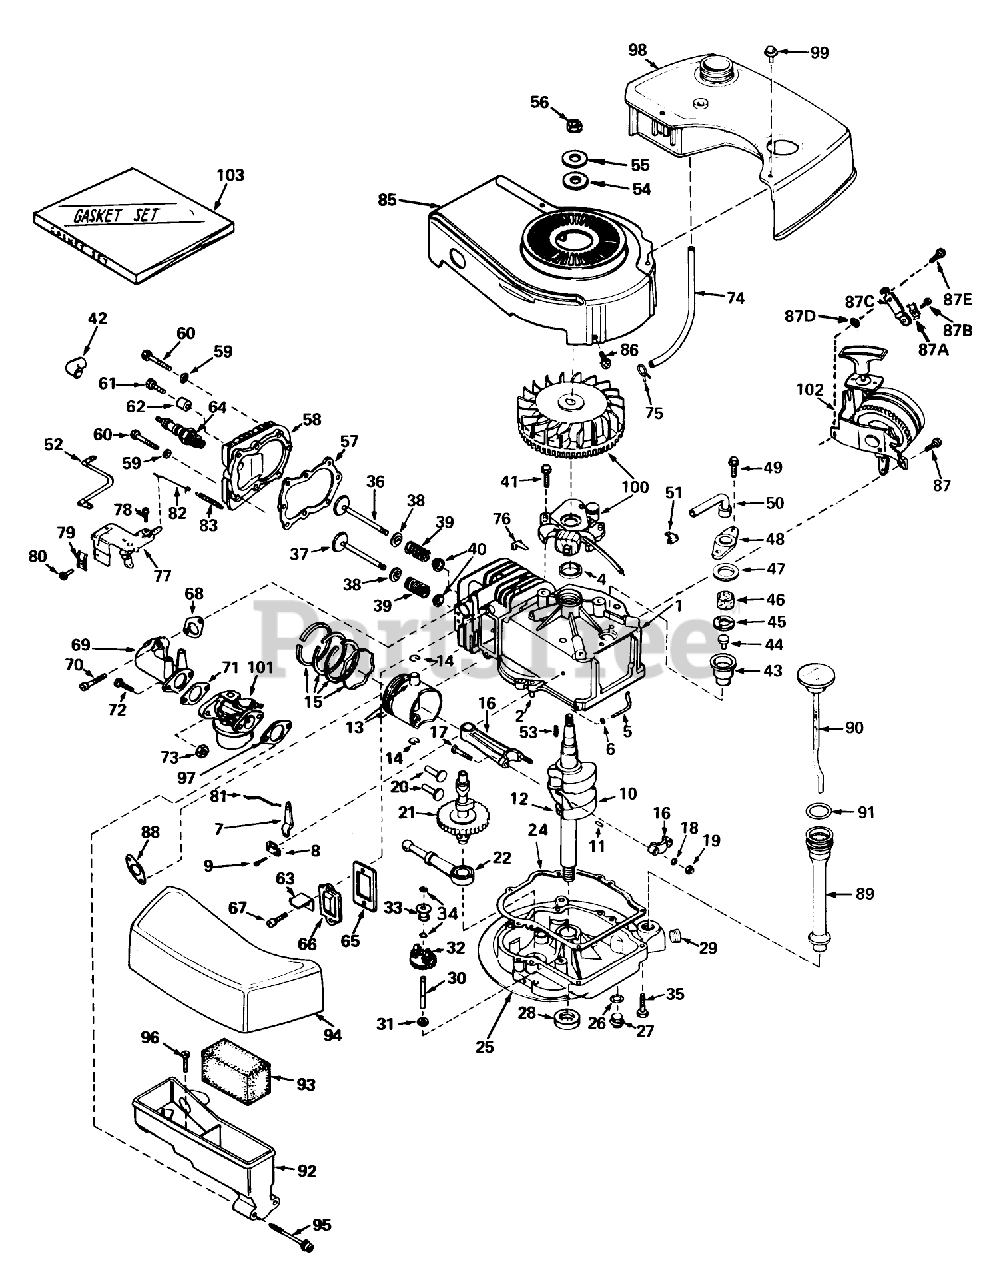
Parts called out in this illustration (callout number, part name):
1	Cylinder Assy. (Incl. Ref. #2, 4 105)
2	Pin-Dowel
4	OIL SEAL
5	Rod, Governor (Incl. No. 36)
6	Washer-Flat
7	Governor Lever
8	Clamp-Lever, Governor
9	Screw
10	Crankshaft Assembly (Incl. Nos. 12 13)
11	Pin, Groove
12	Gear, Crankshaft
13	Piston Pin Assembly (Incl. 2 of No. 14) (.010 Oversize)
13	Piston Pin Assembly (Incl. 2 of No. 14) (.020 Oversize)
14	Ring-Retaining, Piston Pin
15	Ring Set Piston (Std.)
15	Ring Set Piston (.010 Oversize)
15	Ring Set Piston (.020 Oversize)
16	Rod Assy., Connecting (Incl. Ref. #17)
17	Bolt, Connecting
18	Washer
19	LOCKNUT
20	Lifter-Valve
21	Camshaft (Mech. Compression Release)
22	Oil Pump ASM
24	Gasket, Mounting
25	Filter, Air Cleaner
26	Gasket-Oil Drain
27	Plug Oil Drain
28	Seal Oil
29	Plug Oil Drain
30	Shaft-Governor
31	Washer-Flat
32	Governor Gear ASM
33	Spool-Governor
34	Ring-Retaining
35	Screw (1/4-20 x 1-1/4)
36	Valve, Intake (Incl. Ref. #38, 39 40) (Std.)
36	Valve, Exhaust (1/32" Oversize) (Incl. Nos. 8, 9 10)
37	Valve, Exhaust (Standard) (Incl. Nos. 8, 9 10)
37	Valve, Exhaust (1/32" Oversize) (Incl. Nos. 8, 9 10)
38	Cap-Upper Valve Spring
39	Spring-Valve
40	Cap-Valve, Spring
41	Screw
42	Cover-Spark Plug
43	Body Breather Tube
44	Valve Check
45	2000A37 WIZARD ROTA
46	Element-Breather
47	Gasket-Breather
48	Cover Breather
49	Screw, Hex Hd. w/Conical
50	Tube, Breaker
51	Clip, Breather
52	Wire, Ground
53	Key Flywheel
54	Washer Flat
55	Washer, Belleville
56	Nut, Flywheel
57	63573 GIL 42 SNWTHW
58	Head Cylinder
59	Washer
60	Screw
61	Screw Hex Hd. Cap
62	Space
63	Retainer Clip
64	Plug, Spark (J17LM or equiv.)
65	Gasket-Breather
66	Cover-Valve
67	Screw
68	Gasket, Intake
69	Pipe, Intake
70	Screw (1/4-20 x 1)
71	Gasket-Carburetor
73	Nut and Lock Washer (1/4-28)
74	Line-Fuel
75	Clamp-Line, Fuel
76	Clip-Wire
77	Control Assy., Speed
78	Screw (10-24 x 3/4)
79	Conduit
80	Screw (10-32 x 3/8)
81	Link Governor
82	Link Governor Spring
83	Spring Governor
85	Housing, Blower
86	Screw
87	Screw (1/4-20 x 1/2)
87A	Conduit
87B	Screw (10-32 x 3/8)
87C	Bracker
87D	Washer
87E	Screw (1/4-20 X 5/8)
88	Gasket Exhaust
89	Tube, Oil Filler
90	Dipstick, OiI (Incl. No. 91)
91	O-Ring
92	Body Air Cleaner
93	Filer, Air
94	Cove, Air Cleaner
95	Screw Fil Hd.
96	Screw, Hex Hd.
97	Gasket-Air Cleaner
98	Tank Fuel
99	Screw (10-32 x 35/64)
100	Magneto
101	Carburetor
102	Starter
103	53024/VAR.16HP O/P
